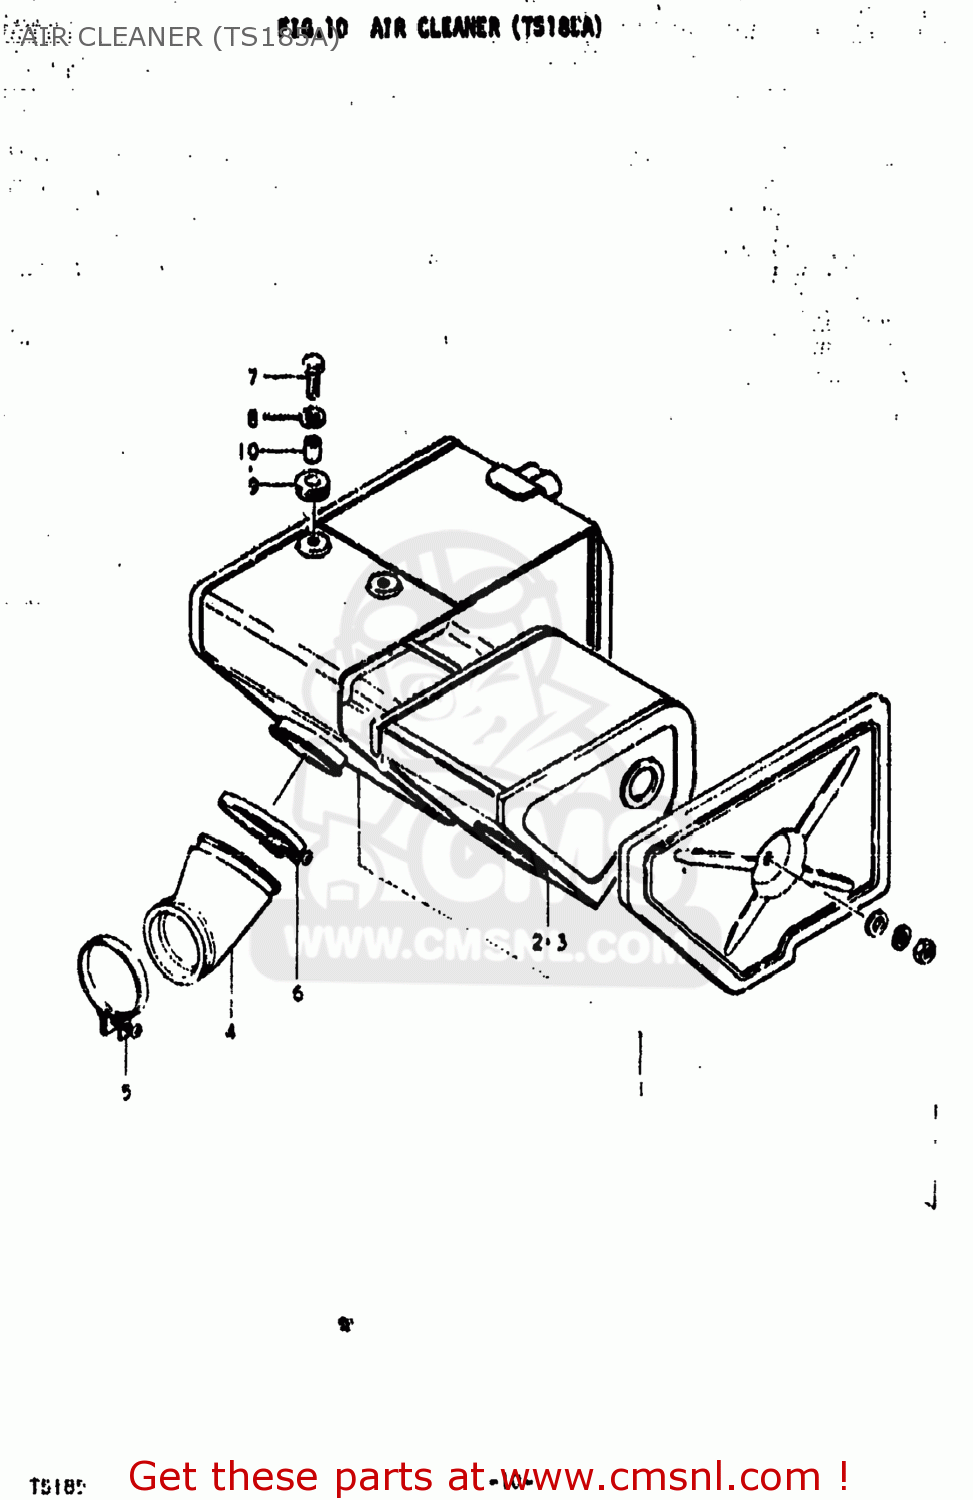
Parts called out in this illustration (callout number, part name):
1	CLEANER ASSEMBLY,AIR
2	FILTER,AIR CLEANER
3	ELEMENT,AIR CLEANER
4	TUBE,AIR CLEANER OUTLET
5	CLAMP
6	CLAMP
7	BOLT
8	WASHER (6.5X20X1.2)
9	CUSHION
10	SPACER (7X9X7)
